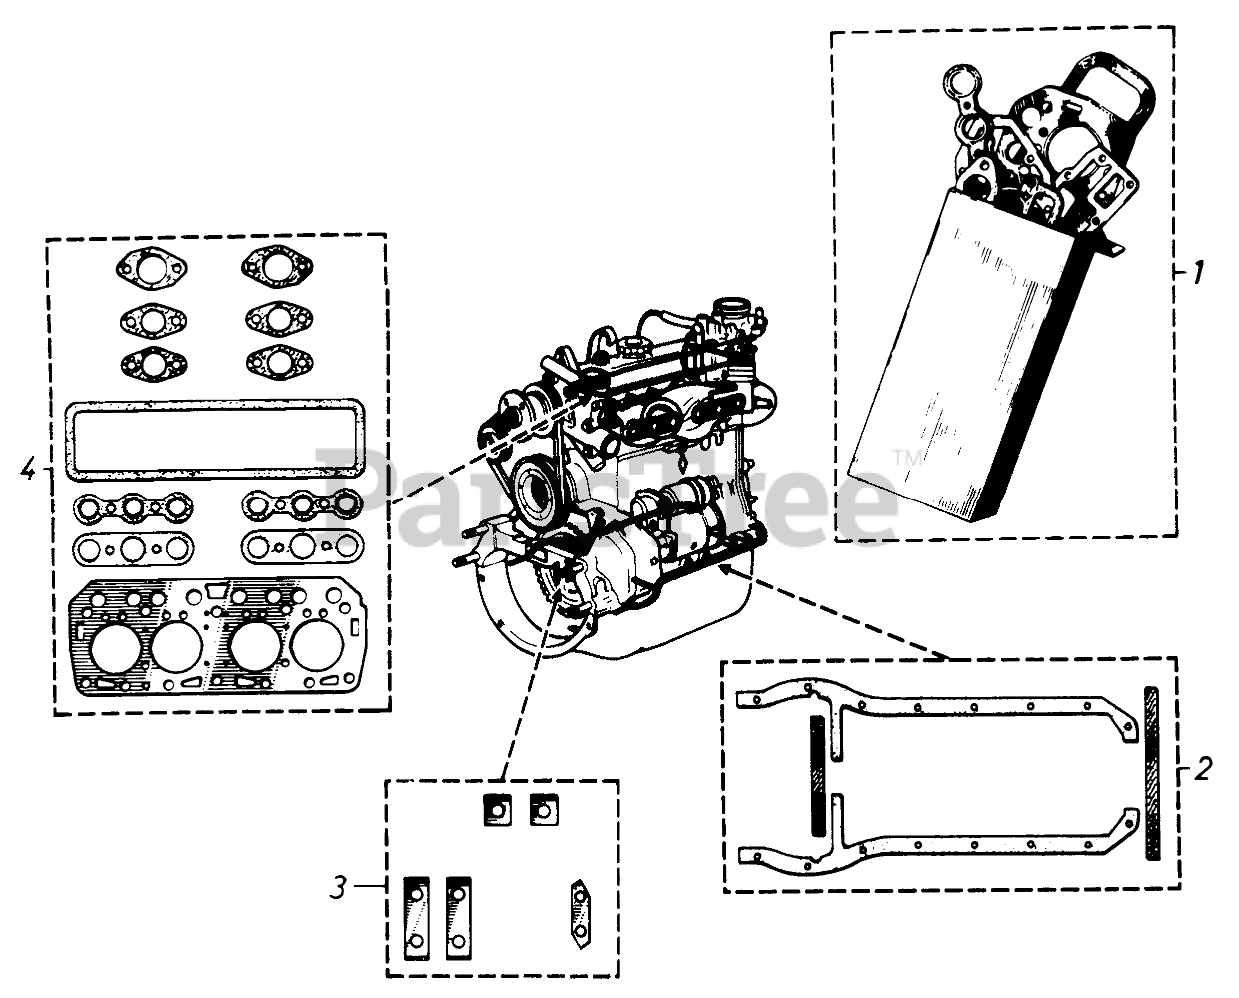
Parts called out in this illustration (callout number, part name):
1	Gasket Set Cpl.
2	Gasket Set
3	Set of Lock Parts
4	Gasket Set
